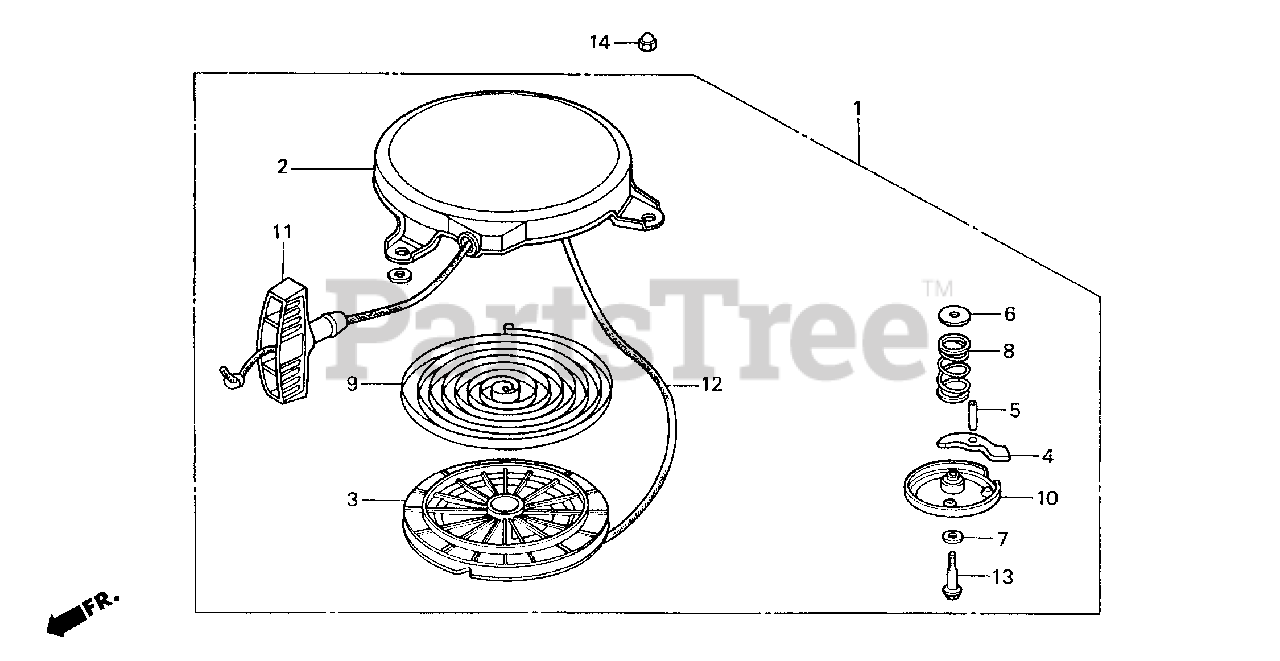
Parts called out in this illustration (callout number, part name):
1	STARTER ASSY., RECOIL
2	CASE, STARTER
3	REEL, STARTER
4	RATCHET, STARTER
5	SHAFT, RATCHET
6	PLATE A, FRICTION
7	PLATE B, FRICTION
8	SPRING, FRICTION
9	SPRING, RETURN
10	COVER, REEL STARTER
11	GRIP, STARTER
12	ROPE, STARTER (#4X65") (N/A: USE ALT P/N 08540-ZG921-11)
13	BOLT, REEL COVER
14	NUT, CAP (6MM)
